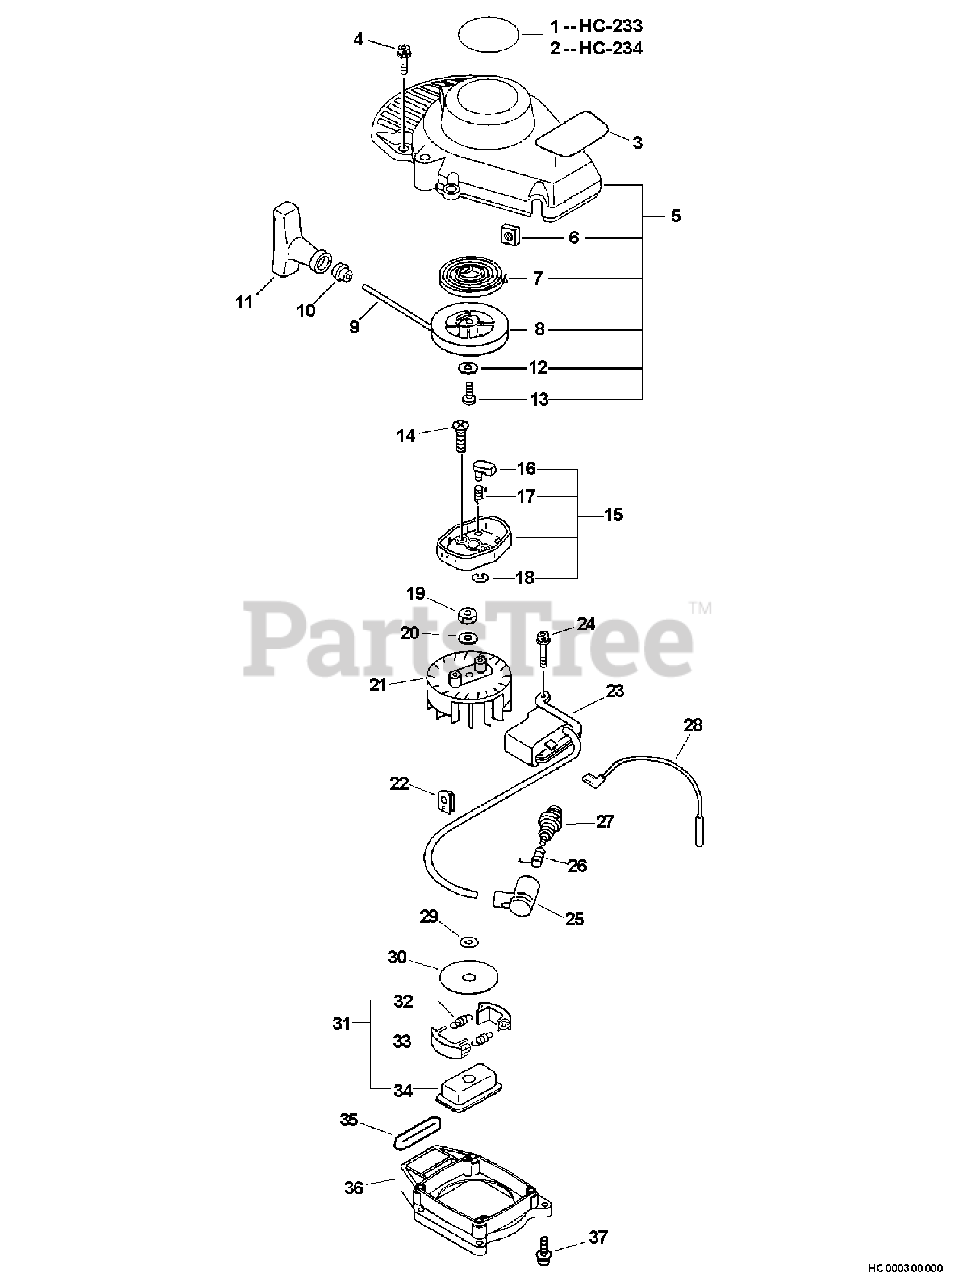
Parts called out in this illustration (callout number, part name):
1	LABEL - MODEL HC-233
2	LABEL - MODEL HC-234
3	LABEL - CAUTION
4	SCREW - 5X16
5	STARTER ASSY
6	NUT - 5 -- SQUARE
7	SPRING, REWIND
8	REEL, ROPE
9	ROPE, STARTER - 3X1000
10	GUIDE, ROPE
11	GRIP, STARTER
12	WASHER
14	SCREW - 6X14
15	STARTER PAWL ASSY
16	PAWL, STARTER
17	SPRING, RETURN
18	RING, RETAINING - 4
19	NUT - LEFT HAND
20	WASHER - 8
21	FLYWHEEL
23	COIL, IGNITION
24	SCREW - 5X16
25	CAP, SPARK PLUG
26	TERMINAL, SPARK PLUG CAP
27	SPARK PLUG -- BPM-7Y
28	LEAD - IGNITION
29	WASHER
30	PLATE, CLUTCH
31	CLUTCH ASSY
32	SPRING, CLUTCH
33	SHOE, CLUTCH
34	HUB, CLUTCH
35	CUSHION, FUEL TANK
36	CASE, CLUTCH
37	SCREW - 4X14
